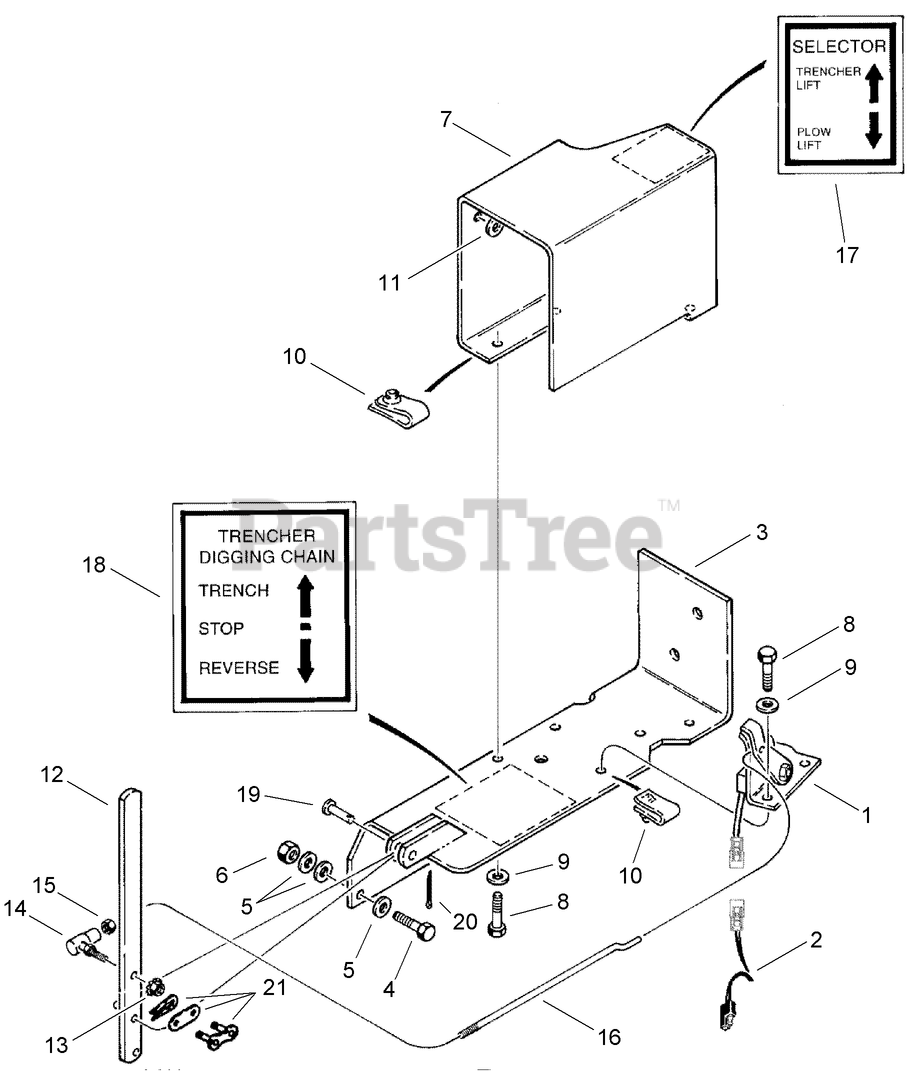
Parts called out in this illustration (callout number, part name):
1	SWITCH ASSEMBLY - Neutral Start
2	HARNESS - Trencher Neutral Start Switch (connect to main wiring harness)
3	BRACKET - Switch and Valve Mounting
4	SCREW-HH
5	WASHER-0.406 x 0.812 x 0.065 in CST ZND
6	NUT-HEX
7	COVER - Neutral Start Switch
8	BOLT-Hex, 5/16 NC x 1-1/4 inch
9	WASHER-FLAT
10	NUT-U TYPE
11	WASHER - Flat, 3/8 x 7/8 x 3/32 inch
12	LEVER-VALVE
13	NUT-KEPS Ext T Washer #10-32 UNF ZP
14	JOINT-Ball
15	NUT - Hex, #10-32 UNF, 303 Stainless Steel
16	ROD-SWITCH, NEUTRAL
17	DECAL - Selector, Trencher Lift/Plow Lift
18	DECAL - Trencher Digging Chain, Trench/Stop/Reverse
19	PIN-CLEVIS
20	PIN - Cotter .062 x .50 in ZND
21	LINK-#50, CONNECT (SINGLE PITCH)
